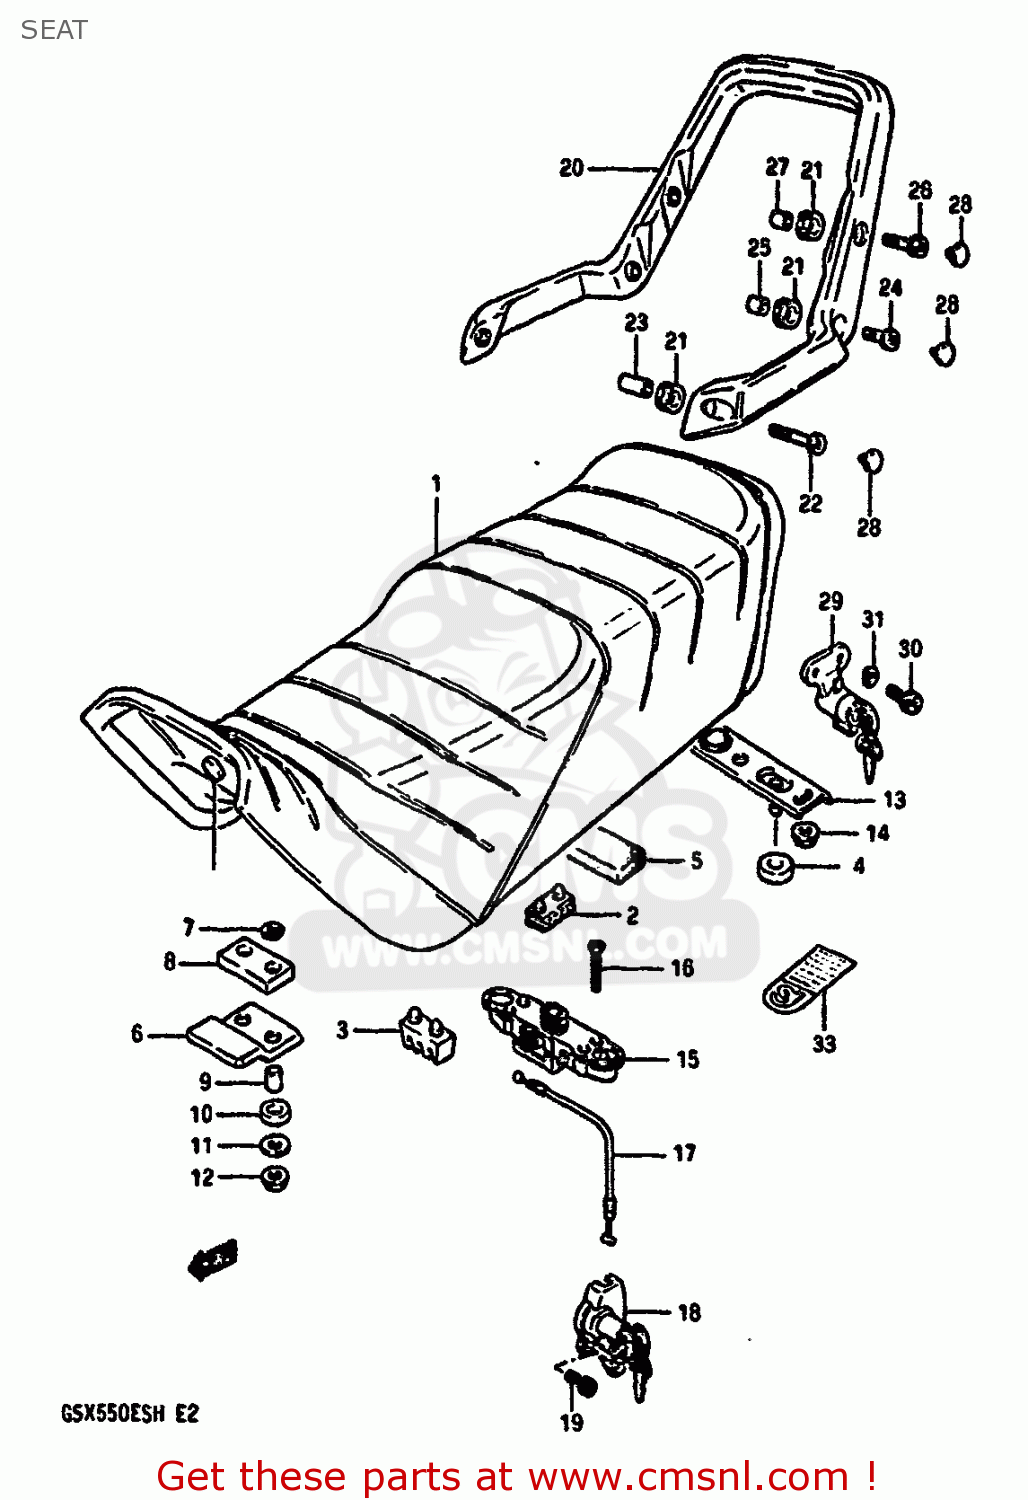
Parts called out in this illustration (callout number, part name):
1	SEAT ASSEMBLY
2	CUSHION,SEAT(40X20X15)
3	CUSHION,SUPPORT(50X25X32)
4	CUSHION,STRIKER
5	CUSHION
6	CUSHION(30X60X10)
7	PLATE,SEAT HOOK,FRONT
8	WASHER
9	CUSHION,SEAT
10	SPACER (6.1X8X12)
11	CUSHION
12	WASHER
13	NUT
14	STRIKER, SEAT LOCK
15	NUT
16	LOCK ASSY,SEAT STRIKER
17	SCREW,6X30
18	CABLE,SEAT LOCK
19	LOCK ASSEMBLY,SEAT & HELMET
20	BOLT
21	HANDLE,PILLION RIDER
22	GROMMET,PILION RIDER HANDLE
23	BOLT
24	SPACER,PILLION RIDER HOLDER
25	BOLT
26	SPACER,PILLION RIDER HOLDER
27	BOLT
28	SPACER,PILLION RIDER HOLDER
29	CAP(OD:10)
30	LOCK ASSEMBLY,HELMET
31	BOLT
32	WASHER,LOCK
33	LABEL,ASBESTOS WARNING
